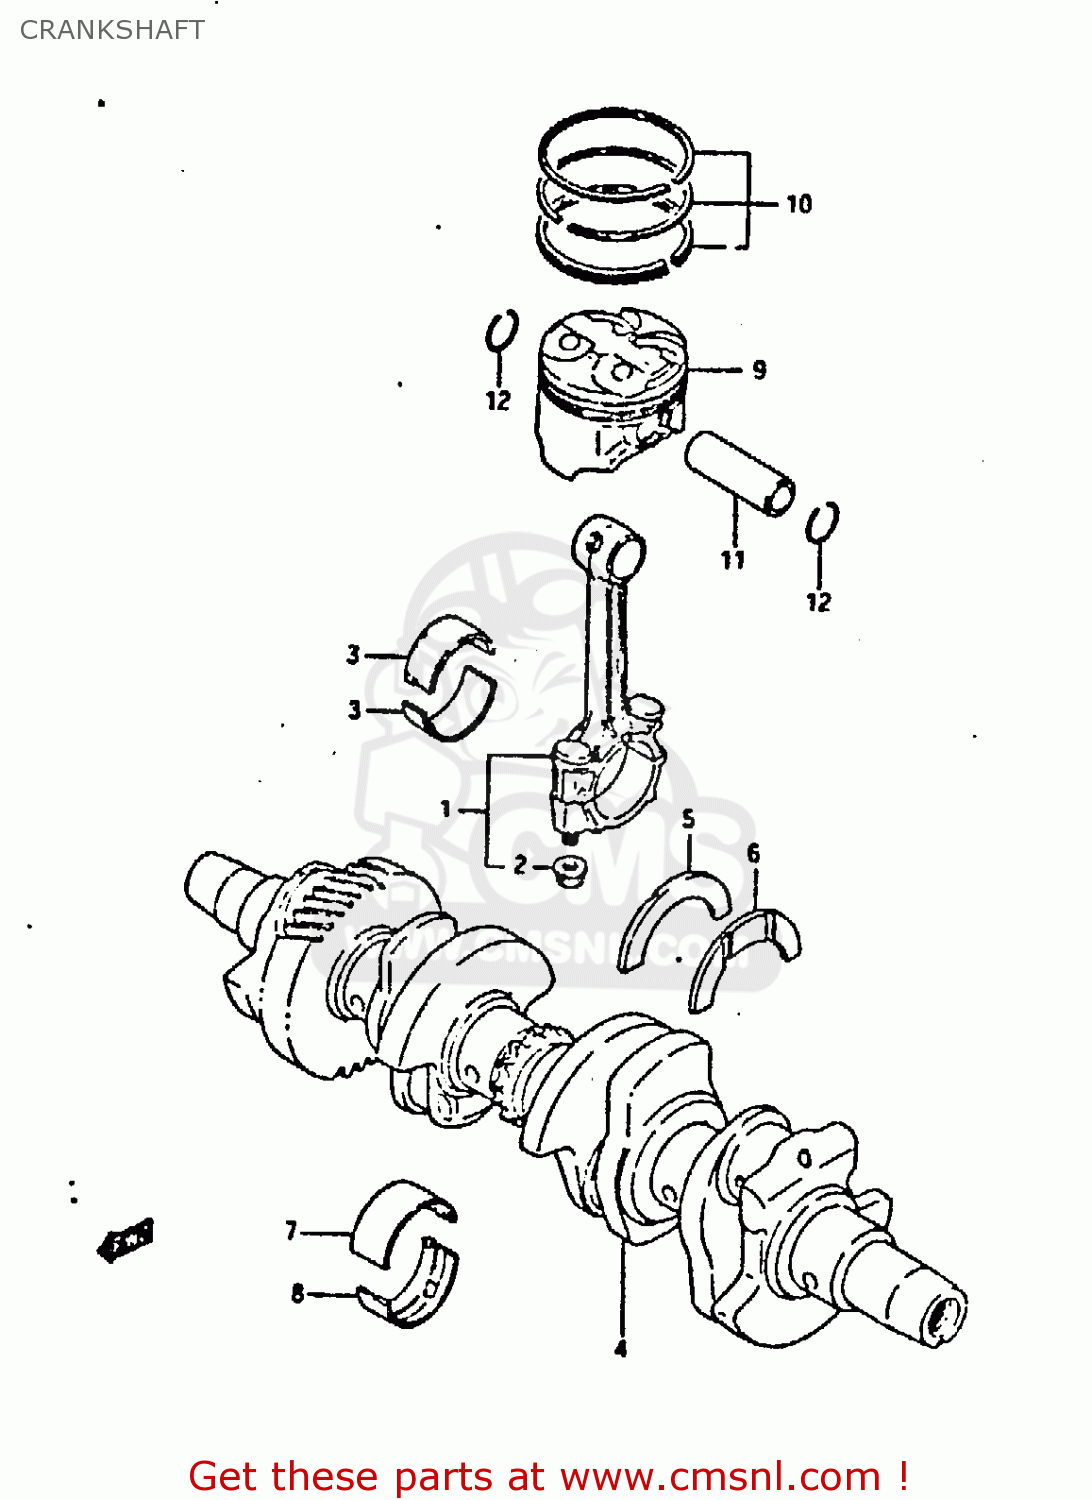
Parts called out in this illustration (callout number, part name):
1	CON.ROD ASSY
2	NUT 7 MM
3	BEARING CR.PIN
4	KRUKASSET
5	PLATE,CRANK THRUST
6	PLATE,CRANK THRUST
7	BEARING,CRANKSHAFT UPR
8	METAL CRANKSHAFT,LOWER
9	ZUIGER
10	RING SET,PISTON
11	PIN,PISTON
12	CIRCLIP
